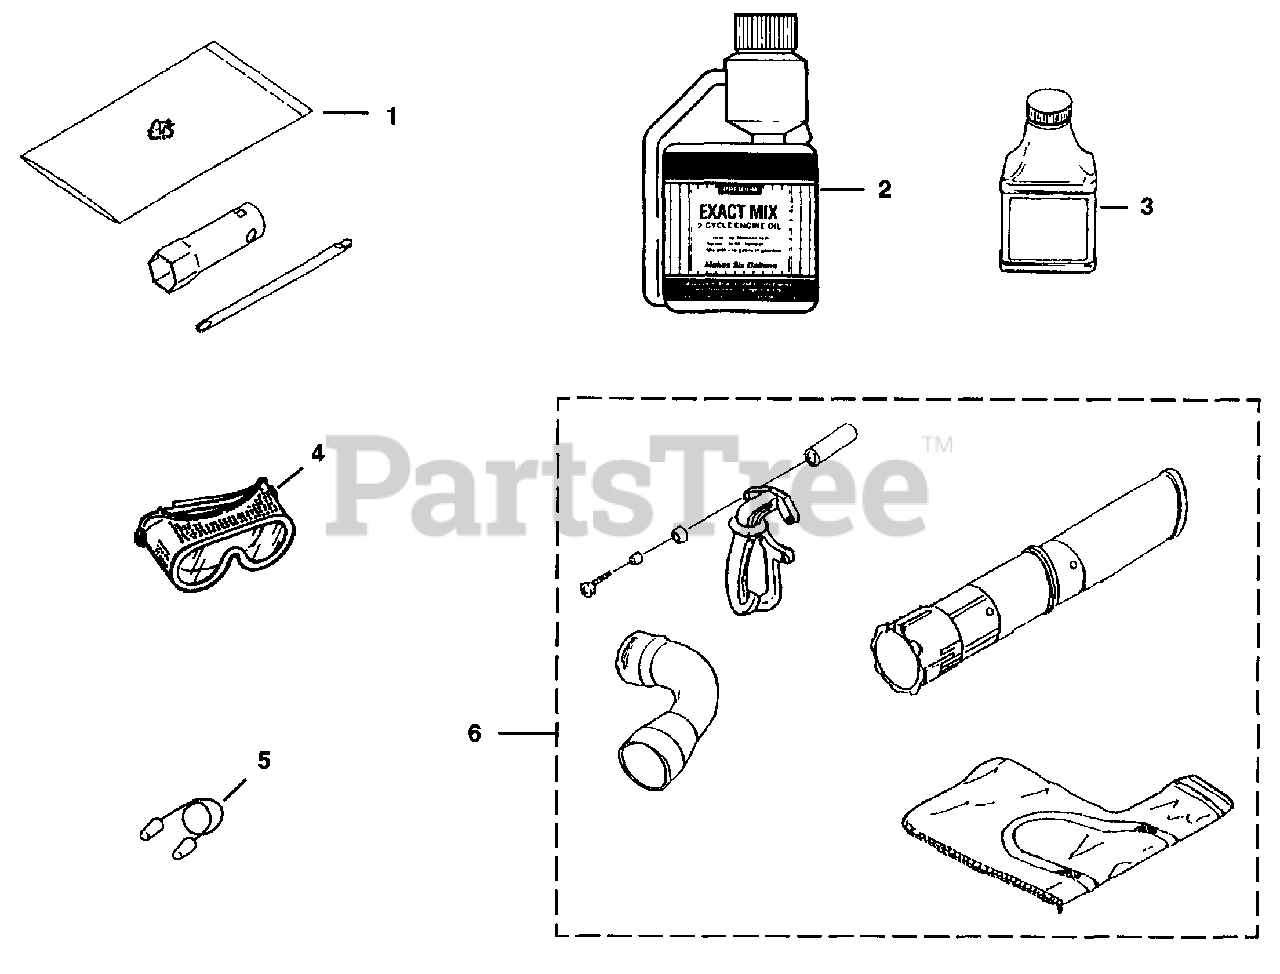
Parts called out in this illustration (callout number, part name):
1	TOOL KIT
2	EXACT MIX (TM) (16 oz.)
3	EXACT MIX (TM) (2.6 oz.)
5	EAR PLUGS
6	VACUUM CONVERSION KIT
7	DECAL KIT
